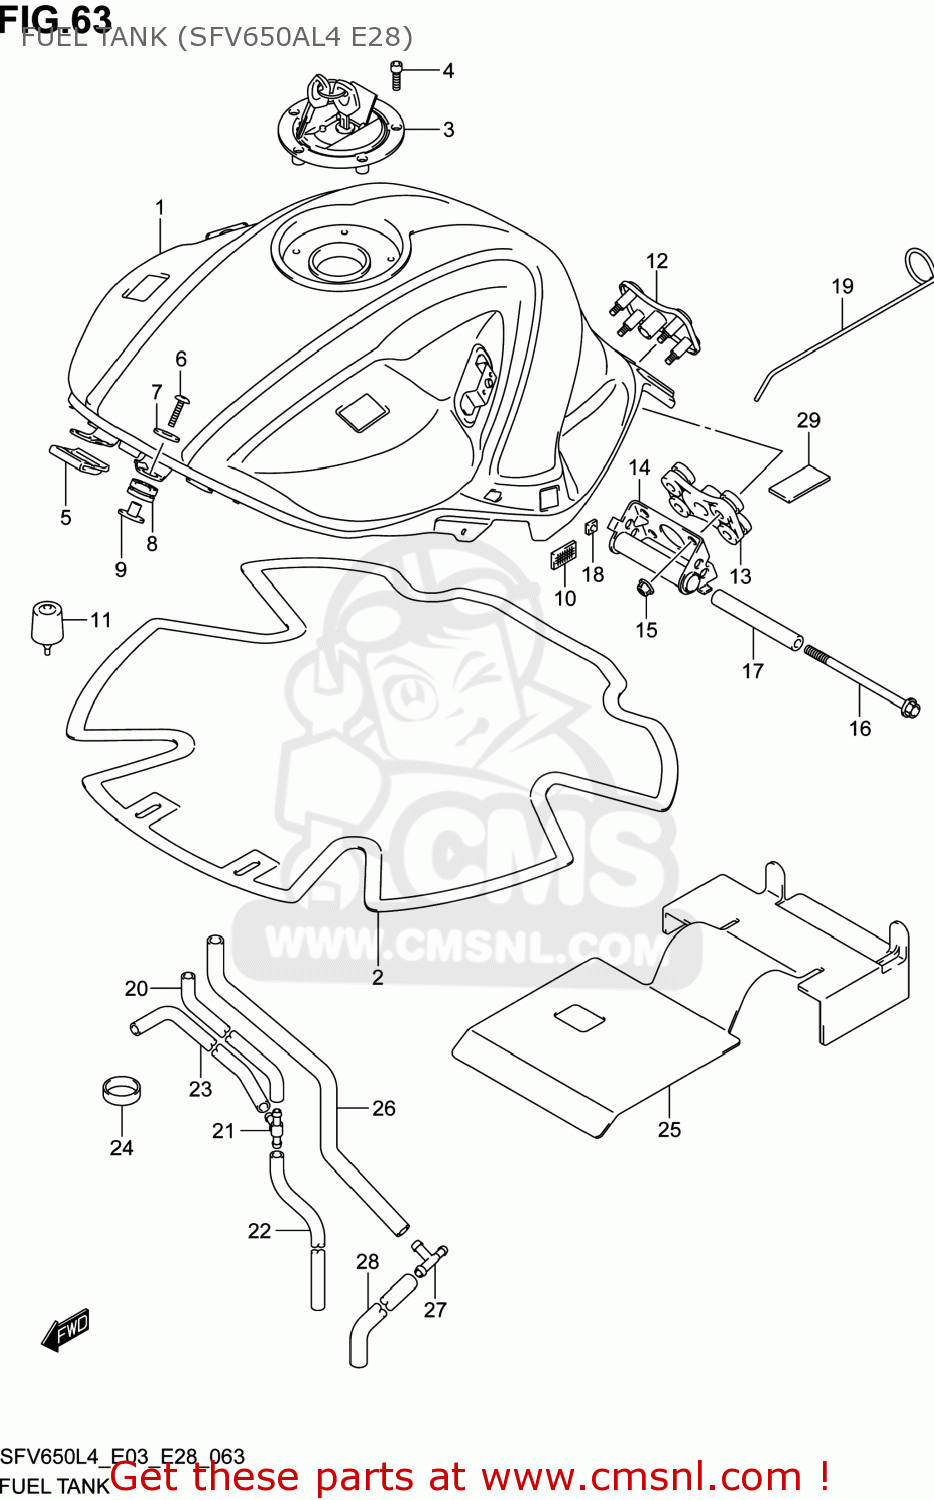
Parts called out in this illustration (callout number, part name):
1	TANK ASSY,FUEL(BLACK)
2	SHIELD,FUEL TANK HEAT
3	CAP SET,FUEL TANK
4	BOLT(5X20)
5	RUBBER,FUEL TANK FR
6	SCREW(6X25)
7	WASHER(6,5X22X1.6)
8	CUSHION,FUEL TANK FR
9	SPACER,FUEL TANK FR
10	FASTENER,FRAME COVER
11	CUSHION,FUEL TANK RR
12	BRACKET,FUEL TANK RR UP
13	CUSHION,FUEL TANK RR
14	BRACKET,FUEL TANK RR
15	NUT
16	BOLT(6X100)
17	SPACER,FUEL TANK RR
18	NUT
19	STAY,FUEL TANK
20	HOSE,FUEL TANK BREATHER NO.1
21	3 WAY
22	HOSE(5X8.2X600)
23	HOSE,VACUUM
24	HOSE(12X16X600)
25	SHEET,HEAT SHIELD RUBBER
26	HOSE,FUEL TANK WATER DRAIN
27	3 WAY
28	HOSE,WATER DRAIN
29	PROTECTOR(30X30X3)
